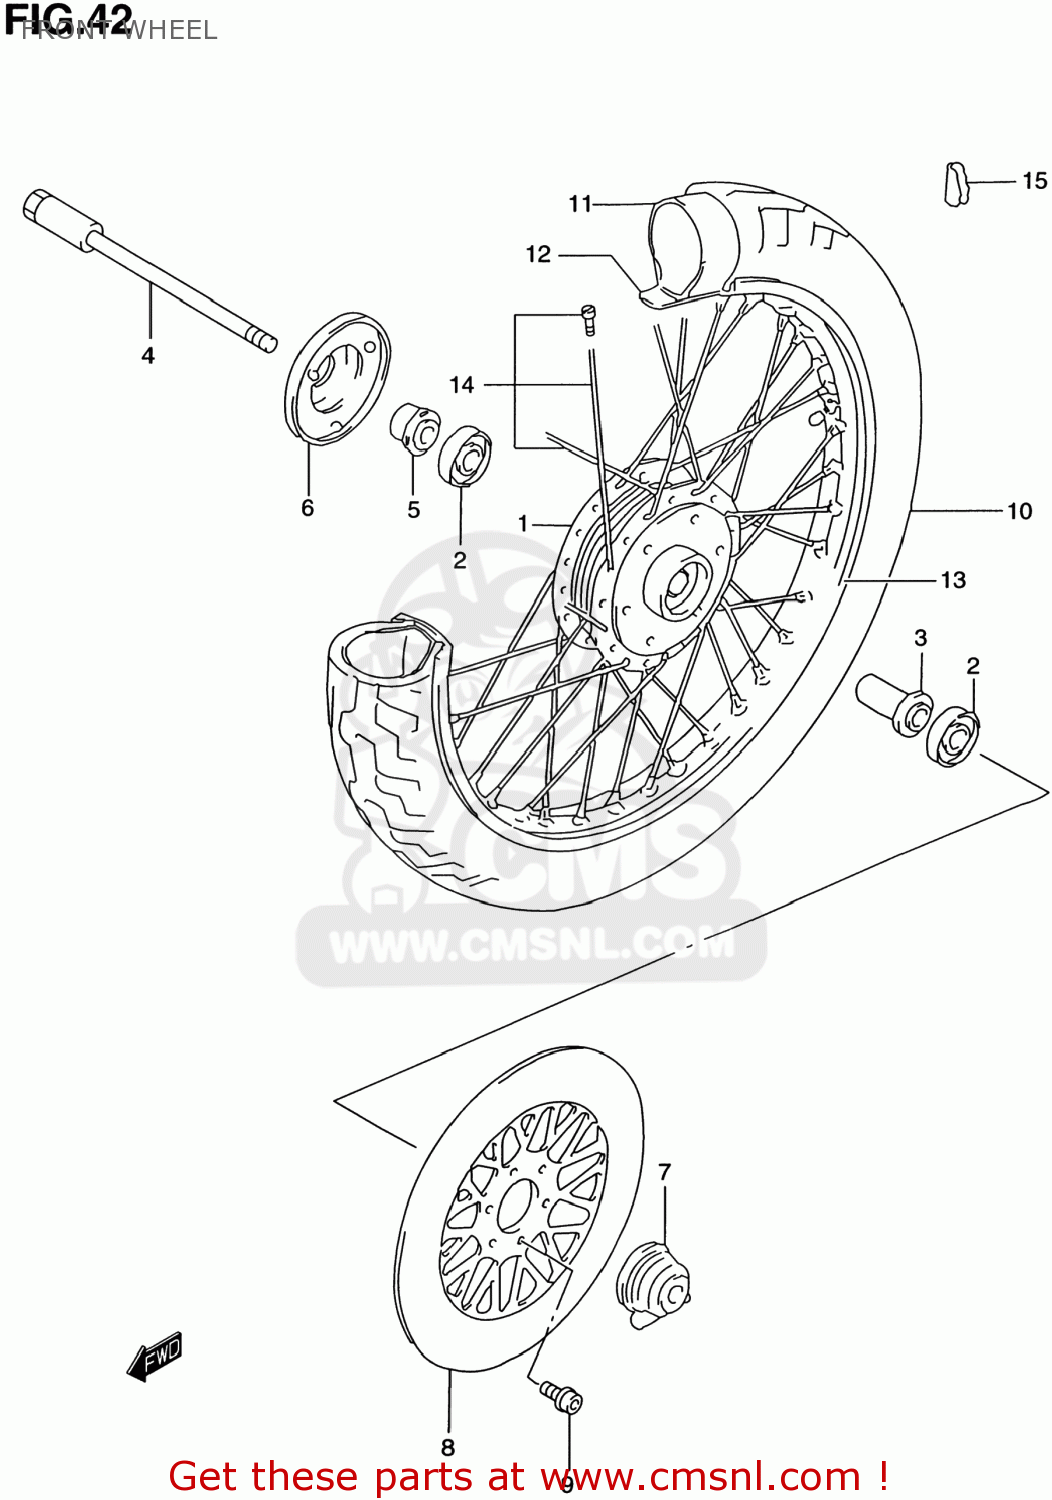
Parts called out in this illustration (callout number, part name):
1	HUB,FR WHEEL
2	BEARING
3	SPACER,FR HUB BEARING
4	AXLE,FR
5	SPACER,FR HUB BEARING,R
6	COVER,FR HUB,R
7	BOX ASSY,SPEEDOMETER GEAR
8	DISC,FR BRAKE
9	BOLT(8X30)
10	TIRE,FR(110/90-16)
11	TUBE ASSY,WHEEL INNER
12	PROTECTOR,WHL INR TUBE
13	RIM,FRONT WHEEL (16XMT2)
14	SPOKE SET,FR WHEEL
15	BALANCER,WHEEL (B)
